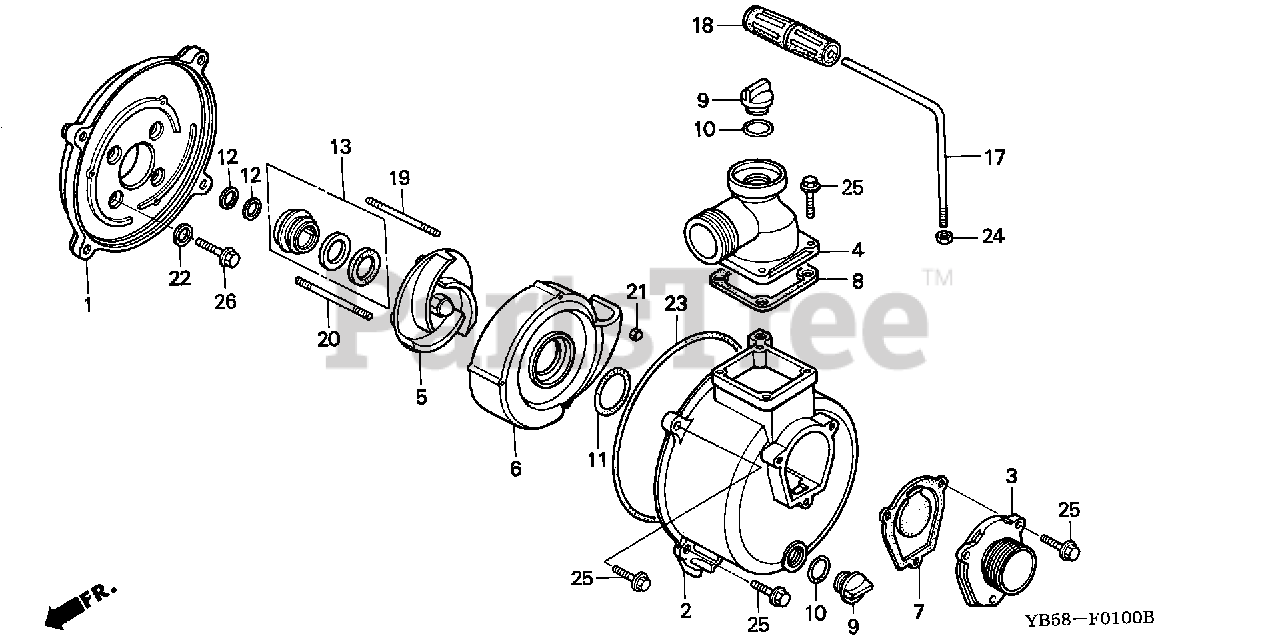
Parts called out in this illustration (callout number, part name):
1	COVER, CASING
2	CASING
3	PIPE, INLET
4	PIPE, OUTLET
6	CASE, VOLUTE
7	VALVE, IN.
8	GASKET, OUTLET
9	CAP, FILLER
10	RING, SEAL (B)
11	O-RING (49X5.7) (NOK)
12	SHIM, ADJUSTER
13	SEAL, MECHANICAL
19	BOLT, STUD (6X50)
20	BOLT, STUD (6X50)
21	NUT, CAP (6MM)
22	WASHER, SEALING (8MM)
23	O-RING (217.5X3.5) (ARAI)
25	BOLT, FLANGE (8X25)
26	BOLT, FLANGE (8X28)
